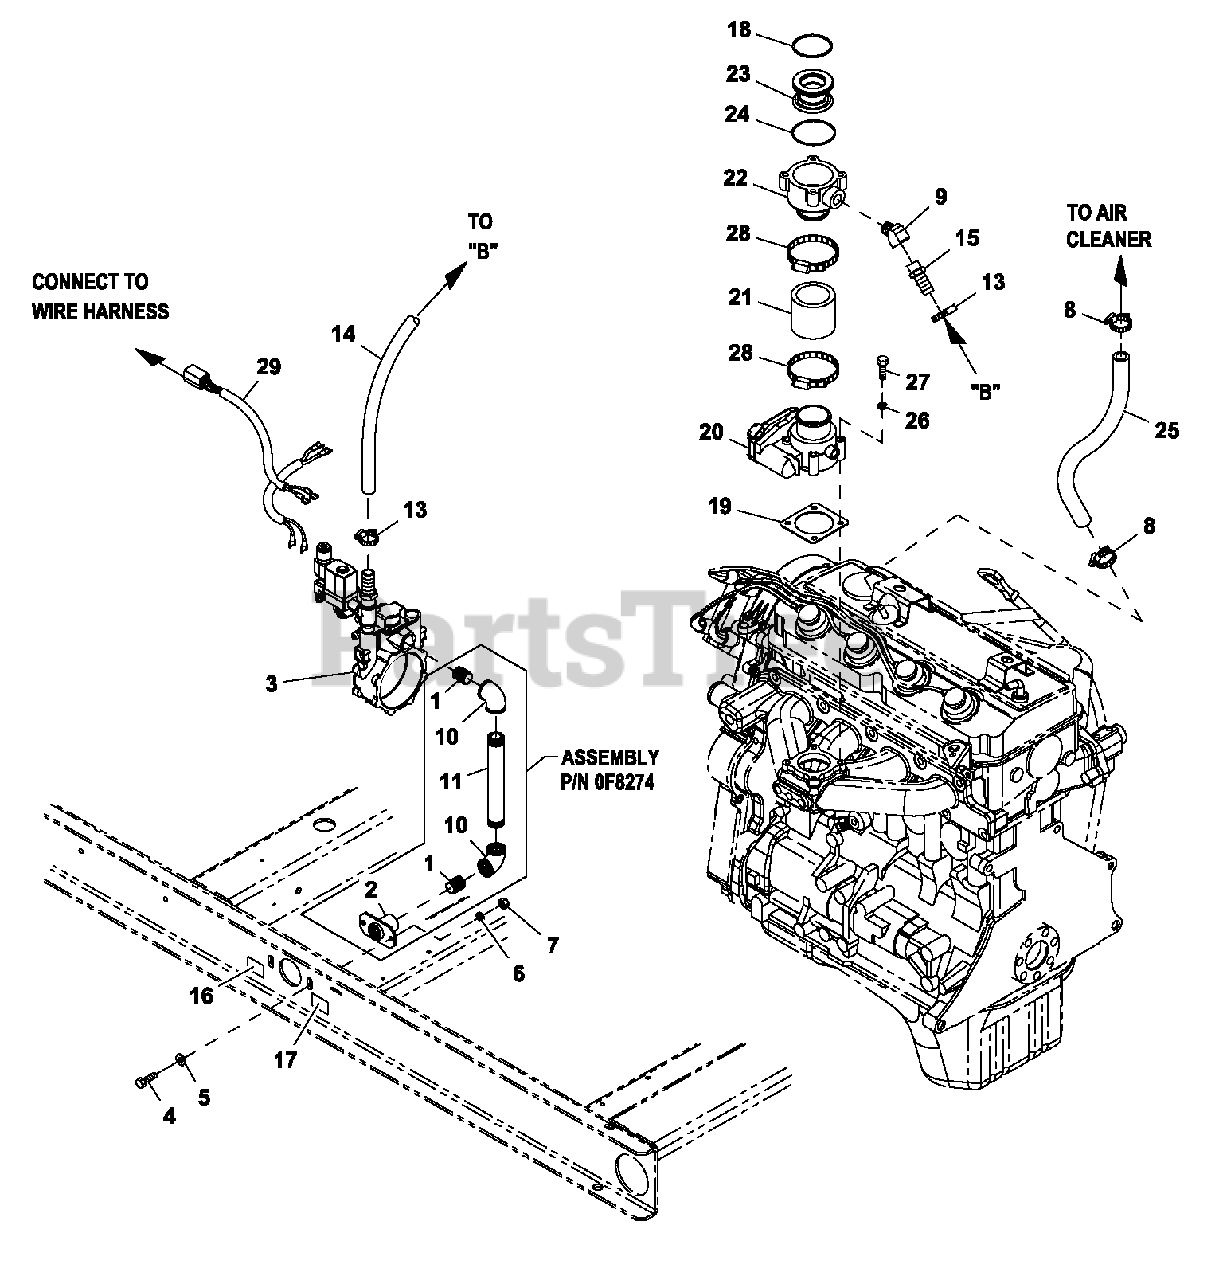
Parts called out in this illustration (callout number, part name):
1	NIPPLE CLOSE 3 /4 X 1 .3 7 5
2	FLANGE FUEL INLET
3	REGULATOR ASSY 2.4L
4	SCREW H H C M8-1.25 X 20 G8.8
5	WAS H ER FLAT 5/16-M8 ZINC
6	WAS H ER LOCK M8-5/16
7	NUT H EX M8-1.25 G8 CLEAR ZINC
8	CLAMP H OSE #5.5 .62-.62
9	STREET EL 45D 1/2 NPT BRASS
10	ELBOW 90D 3/4 NPT
11	NIPPLE PIPE 3/4 NPT X 7
13	CLAMP H OSE # 1 0 .5 6 -1 .0 6
14	H OSE 3/4 ID LPG & NG (18" LG)
15	BARBED STR 1/2 NPT X 3/4
16	DECAL INLET PRESSURE
17	DECAL FUEL INLET NG (NATURAL GAS APPLICATION)
18	O-RING 45.63 ID X 2.62 WIDT H
19	GASKET BOSCH 32
20	ACTUATOR BOSC H 40 GOVERNOR
21	H OSE COOL 2 IN ID 20R4
22	MIXER ACTUATOR 40MM MAC H INED
23	VENTURI TH ROTTLE 26MM
24	O-RING 47.625 ID X 2.38 WID T H
25	H OSE 3/8 ID SINGLE BRAID (18" LG)
26	WAS H ER LOCK M6-1/4
27	S C R EW S H C M 6 -1 .0 X 4 5 G12.9
28	CLAMP H OSE #28 1.32-2.25
29	HARN FUEL JUMPER SINGLE REG
